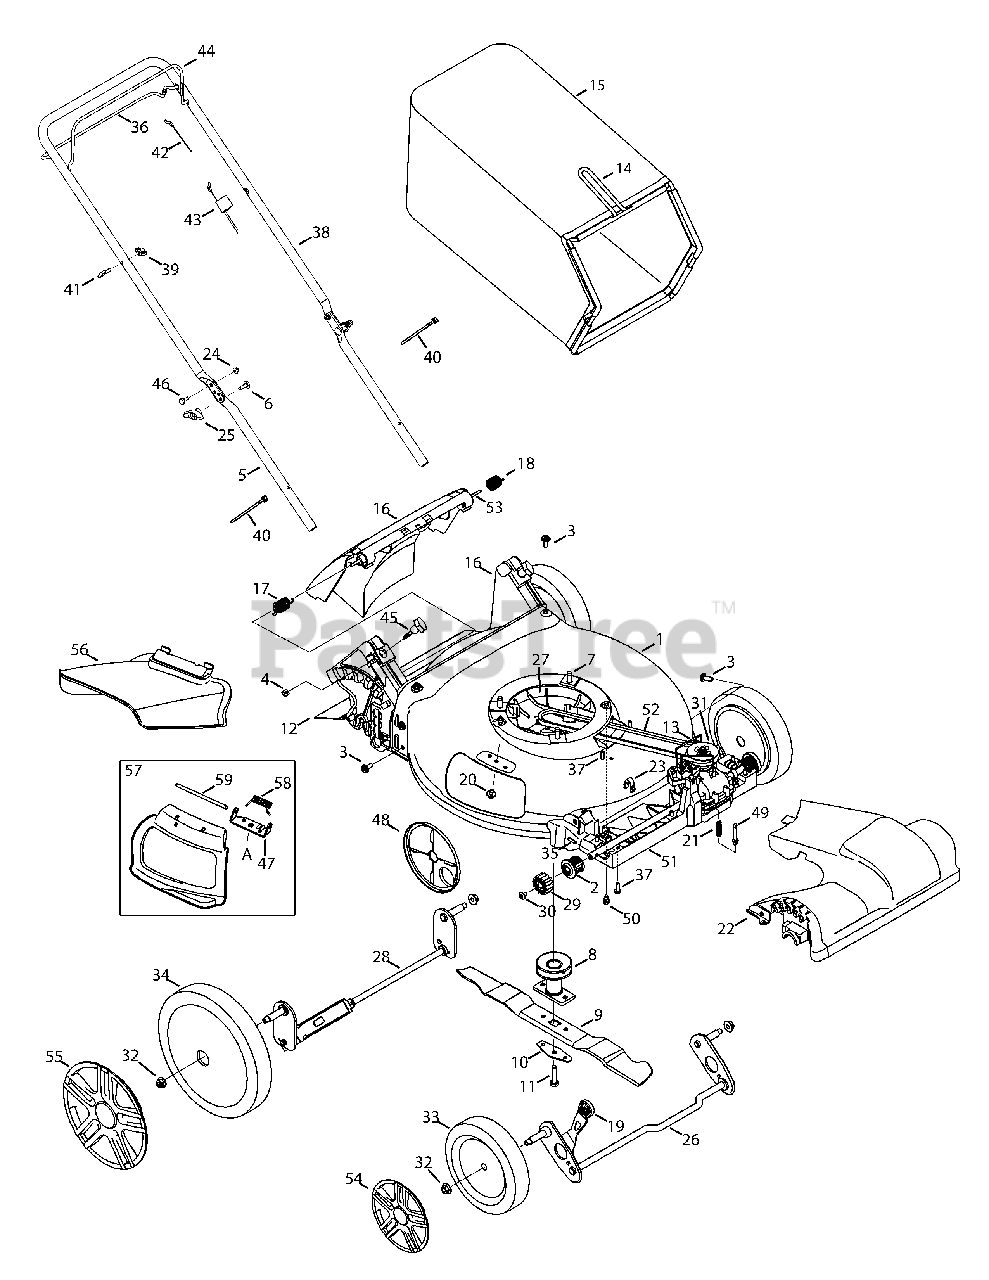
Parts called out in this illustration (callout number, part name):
2	Bearing Assembly
3	Screw, 5/16-14 x .750
4	Nut, Sq., 1/4-20
5	Lower Handle
6	Carriage Screw ,5/16-18
7	Screw, 3/8-16 x 1.00
8	Blade Adapter
9	Mulching Blade
10	Blade Bell Support
11	Screw, 3/8-24 x 1.50
12	Trailing Shield
13	Transmission Wire
14	Grass Catcher Frame
15	Grass Bag (Yardman)
16	Rear Discharge Door Assembly
17	Torsion Spring - RH
18	Torsion Spring - LH
19	Adjustment Lever Knob
20	Screw, 1/4-20 x .500
21	Compression Spring
22	Front Cover
23	Front Axle Clip
24	Nut, Flange Lock, 1/4-20
25	Wing Knob
26	Front Axle Assembly
27	Engine Baffle
28	Rear Axle Assembly
29	Spur Gear, 14T - RH
29	Spur Gear, 14T - LH
30	Screw, 1/4-20 x .390
31	Transmission Assembly
32	Flange Lock Nut, 3/8-16
33	Front Wheel, 8 x 1.8, Bar, Gray
34	Rear Wheel, 11 x 1.75, Bar, Gray
35	Dowel Pin
36	Drive Control
37	Screw, 1/4-15 x .750
38	Upper Handle, Adjustable
40	Cable Tie
41	Rope Guide
42	Control Cable
43	Drive Cable
44	Blade Control
45	Wing Nut
46	Sldr. Screw, .375 x .126 x 1/4-20
47	Chute Deflector Bracket
48	Wheel Dust Cover
49	Spring Body
50	Scr., Shldr., 1/4-20 x .50
51	Lower Tray
53	Pivot Rod
54	Hubcap, Gray
55	Hubcap, 11", Gray
56	Side Discharge Chute
57	Mulch Plug (Incl. 47,58,59)
58	Torsion Spring
59	Hinge Pin
